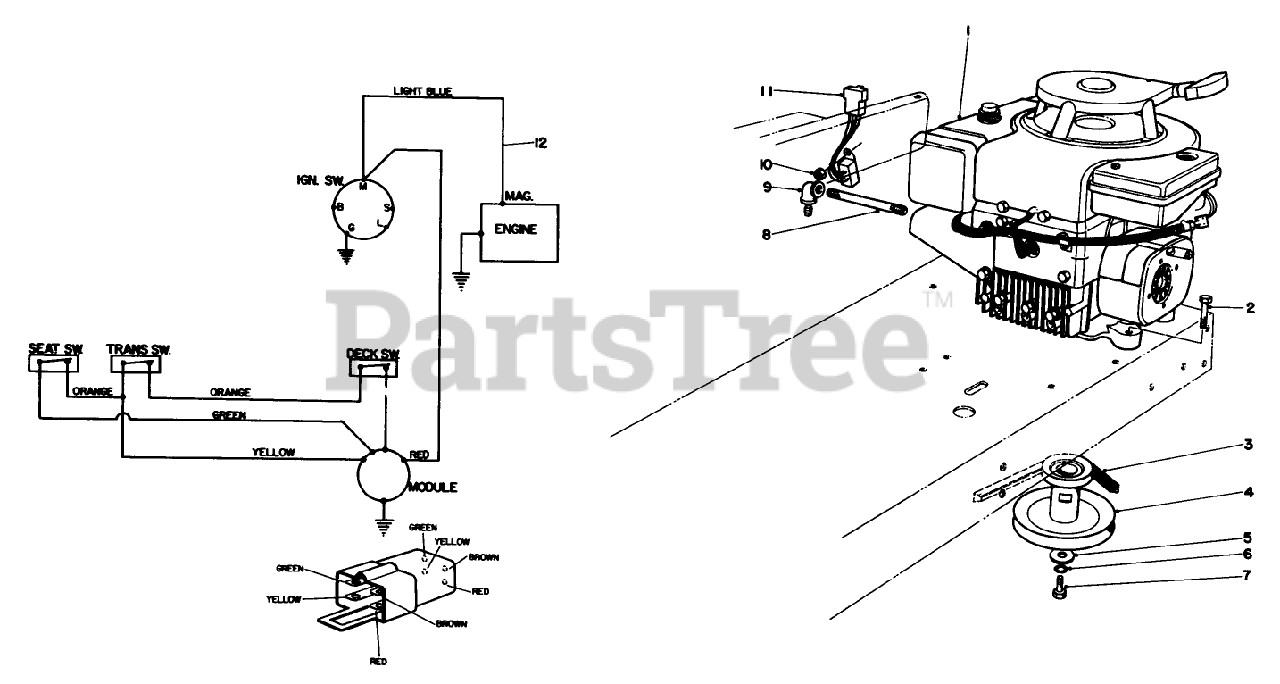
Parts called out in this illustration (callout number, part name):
1	Engine
2	SCREW-HH
3	V-BELT, TRACTION
4	PULLEY
5	WASHER
6	WASHER-LOCK
7	SCREW-HH
8	NIPPLE
9	ELBOW-90 DEGEE
10	NUT-LOCK, CONE
